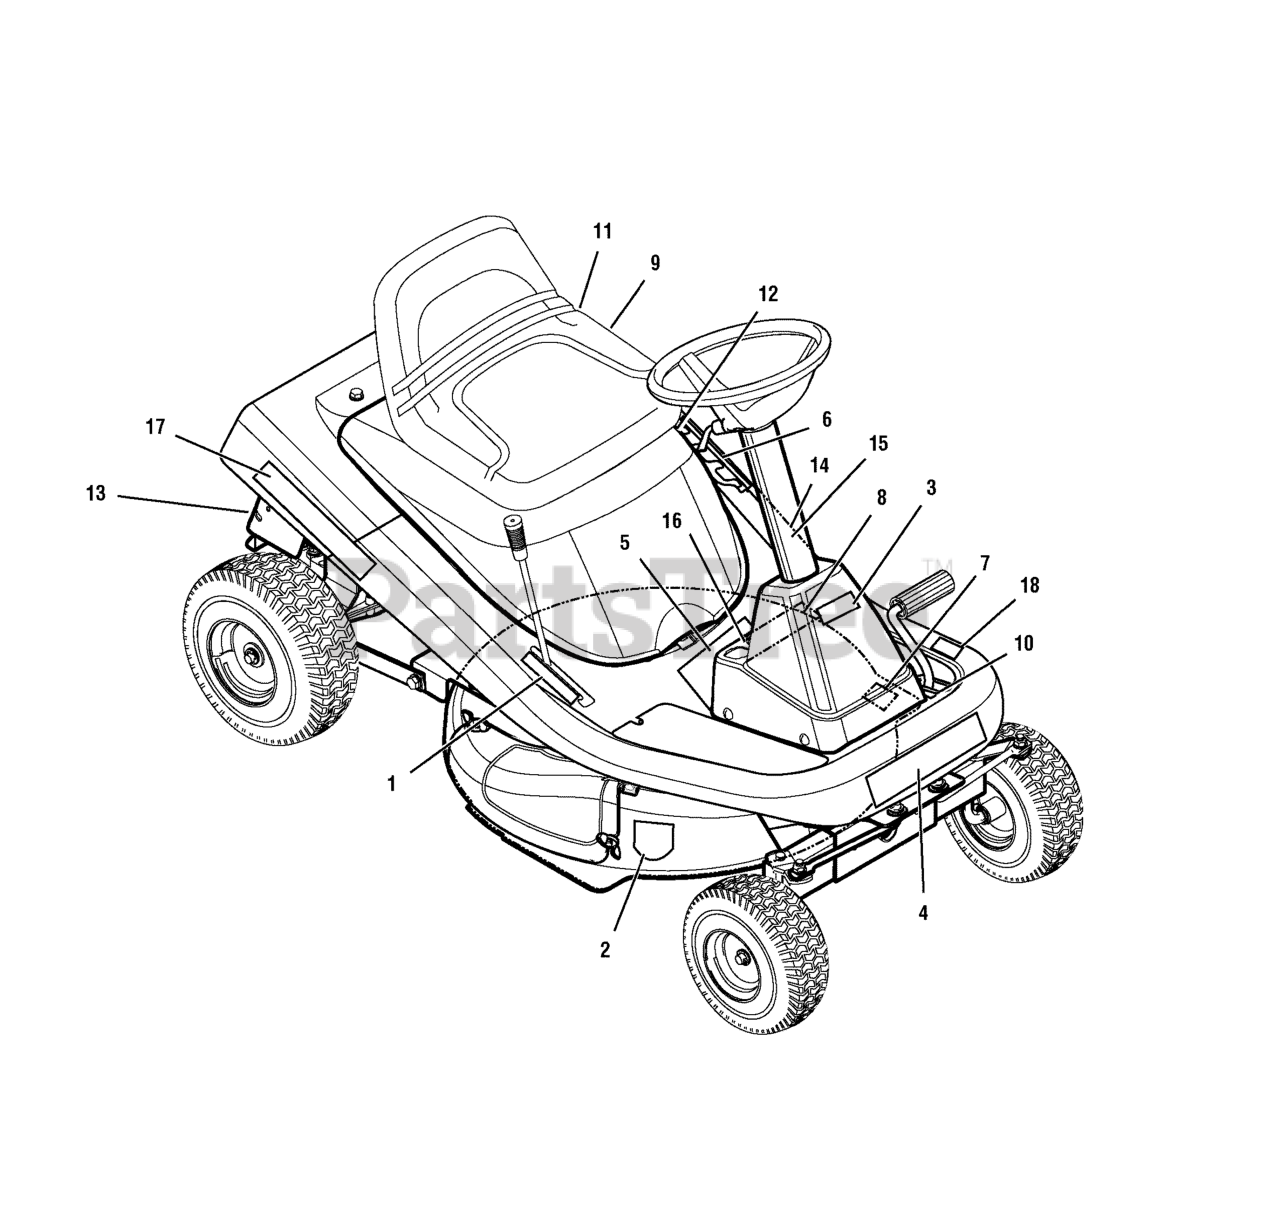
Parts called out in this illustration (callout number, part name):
1	DECAL, Engagement
2	DECAL, Cut Finger Symbols
3	DECAL, Hayter Emblem
4	DECAL, M10/30
5	DECAL, Warning, Export
6	DECAL, Height Adjust, 6 Positions
7	DECAL, No Step, Export
8	DECAL, Park Brake Symbol
9	DECAL, Throttle Control
10	DECAL, Clutch/Brake XPT
11	DECAL, Gas Gauge
12	DECAL, Heat Shield Warning
13	DECAL, Warning Load Limit, Export
14	DECAL, Warning Pinch Point
15	DECAL, Deck Level
16	DECAL, Decal Auto Disconnect
17	DECAL, Hayter Heritage
18	DECAL, 100db, Export
